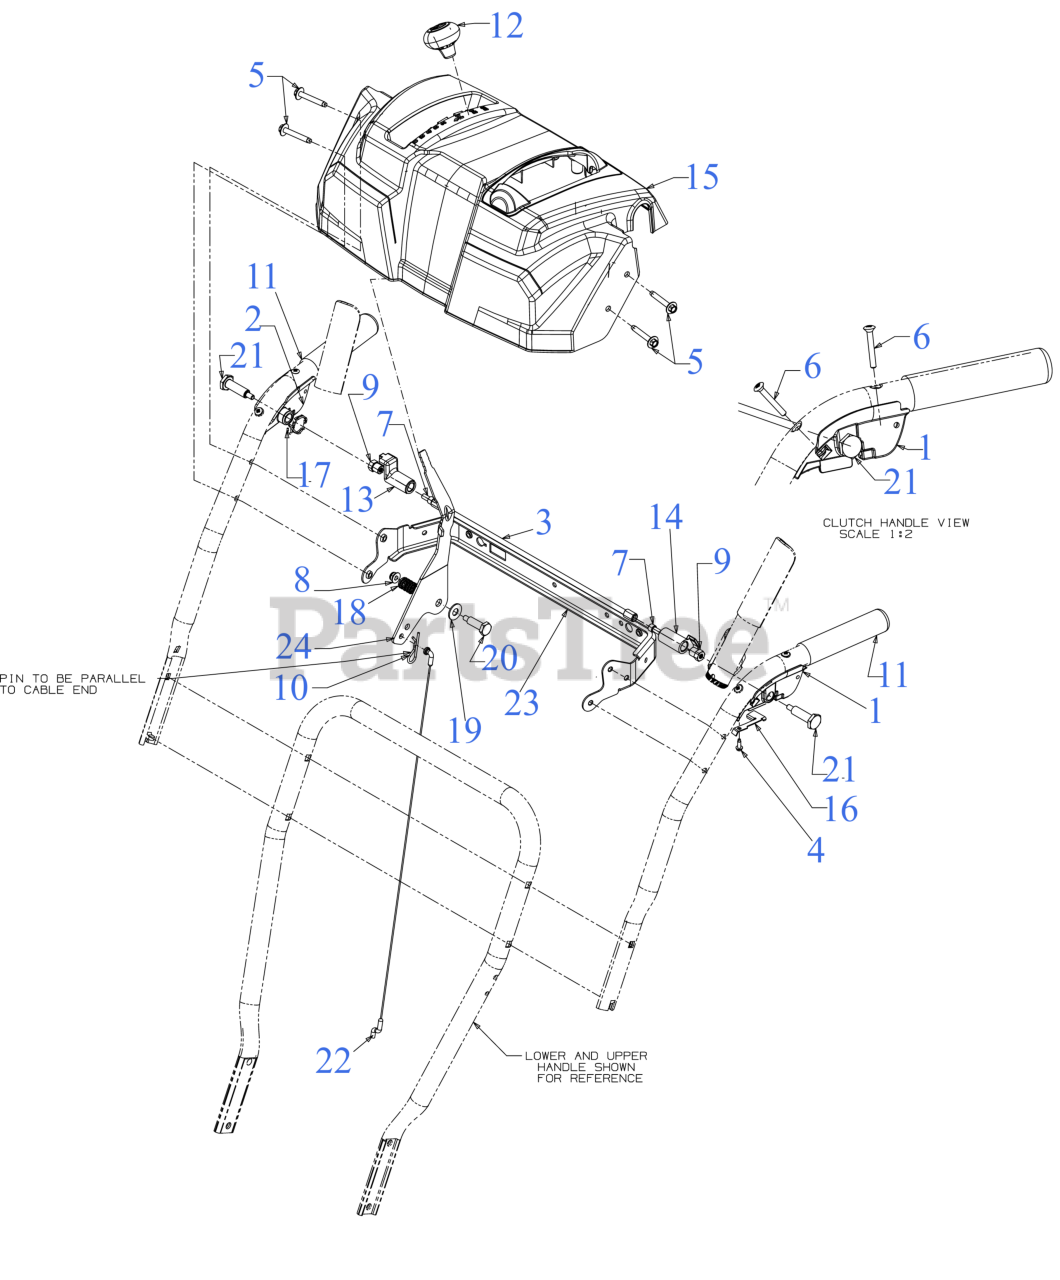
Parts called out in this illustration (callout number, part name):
1	CLUTCH LOCK HANDLE ASSEMBLY (LH)
2	CLUTCH LOCK HANDLE ASSEMBLY (RH)
4	SCREW #8-16 x .50
5	SCREW 1/4-20 x 1.625
6	SCREW #10-24 x 1.375
7	SCREW 1/4-20 x .50
8	FLANGE LOCK NUT
9	HEX NUT W/PATCH
10	INTERNAL COTTER PIN
12	SHIFT KNOB
14	CLUTCH LOCK CAM
15	HANDLE PANEL (W/O LIGHT)
16	CLUTCH SPRING
17	TORSION SPRING
18	COMPRESSION SPRING
19	FLAT WASHER
20	SHOULDER SCREW
21	SHOULDER SCREW .437 x 1.345 1/4-20
22	SPEED SELECTOR CABLE (PLASTIC)
